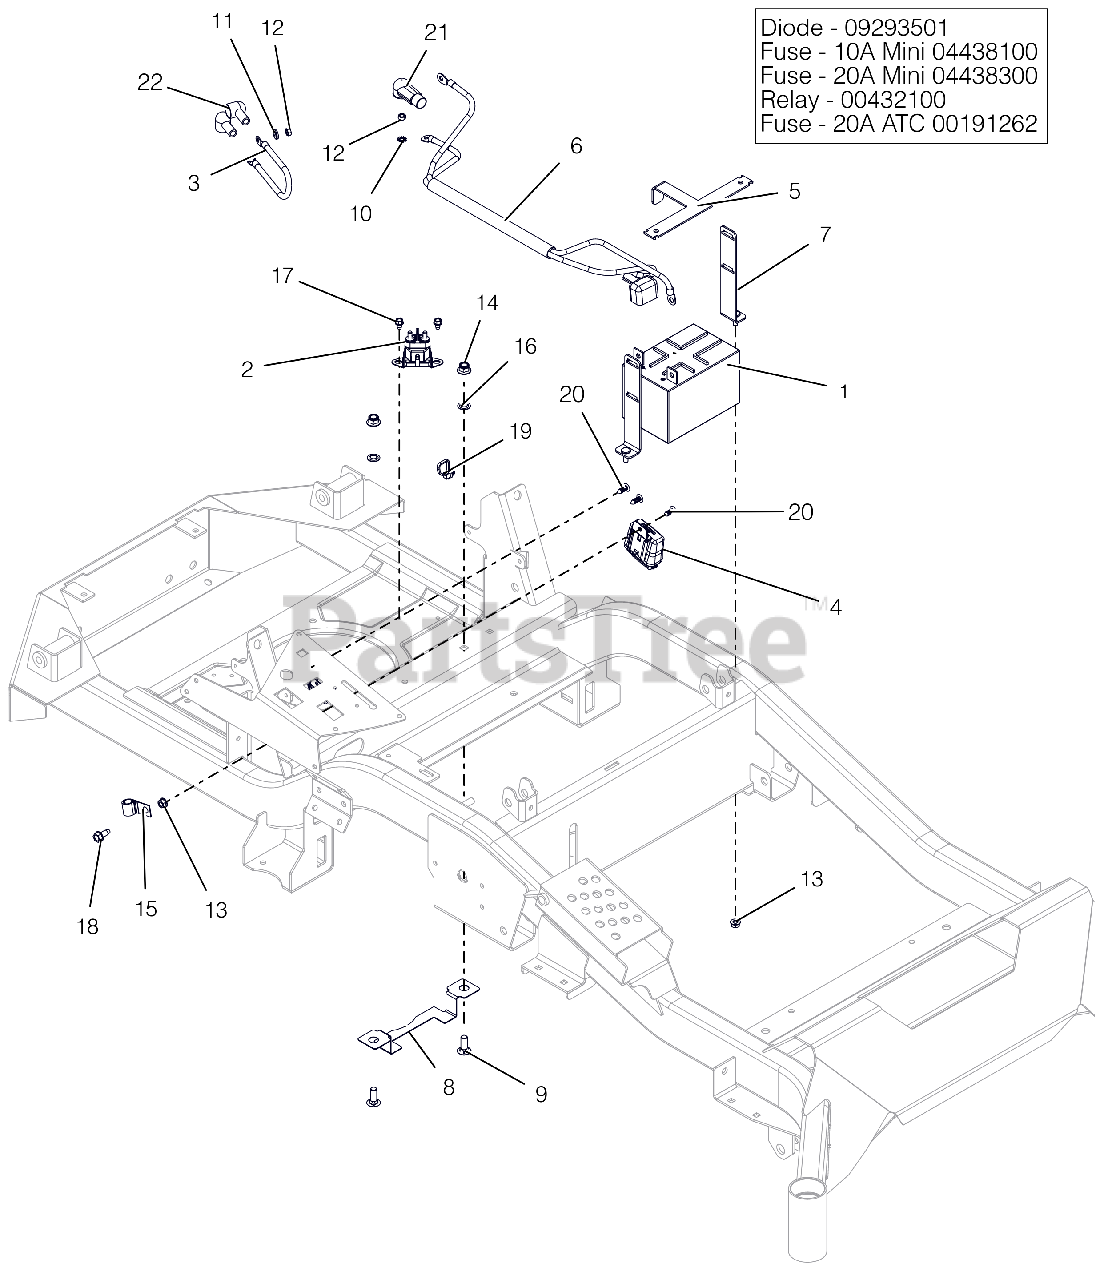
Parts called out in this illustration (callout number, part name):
1	BATTERY, 12V 12A-190CCA
2	SOLENOID, STARTER (SEALED)
3	CABLE, POS W/(2)1/4 RING 9.0LG
4	HARNESS, WIRE
4	DIODE, CONNECTOR SHELL
4	FUSE,10 AMP MINI-ATC
4	FUSE,20 AMP MINI ATC
4	RELAY,SEALED W/DIODE
4	FUSE, 20 AMP BLADE S/O
5	BRKT, BATTERY TIE DOWN
6	HARNESS, BATTERY HD
7	WMT,BATTERY MOUNT HOLD DOWN
8	GUARD, ELECTRICAL HARNESS
9	@BLT-RDHDSQNK .38-16X1.00 G5YZ
10	@WSHR-LK-EXT.262X.502X.026YWZC
11	@WSHR-LK .31X.078 REG YWZC
12	NUT-HEX M6X1.0 YWZC
13	@NUT-LK-TOP-FLG .25-20 YWZC
14	@NUT-LK-NYL-FLG .38-16 YWZC
15	J-CLAMP
16	NUT-PUSH .38 DIA. PAL ZINC
17	@SCR-TAP .25-20X.37 HWH YWZ TR
18	@SCR-TAP .31-18X.75 HWH TR YWZ
19	CABLE TIE W/ TREE (.25 HOLE)
20	RIVET, .25 NYLON PANEL
21	BOOT, .65ID POS
22	BOOT, EYELET TERMINAL
